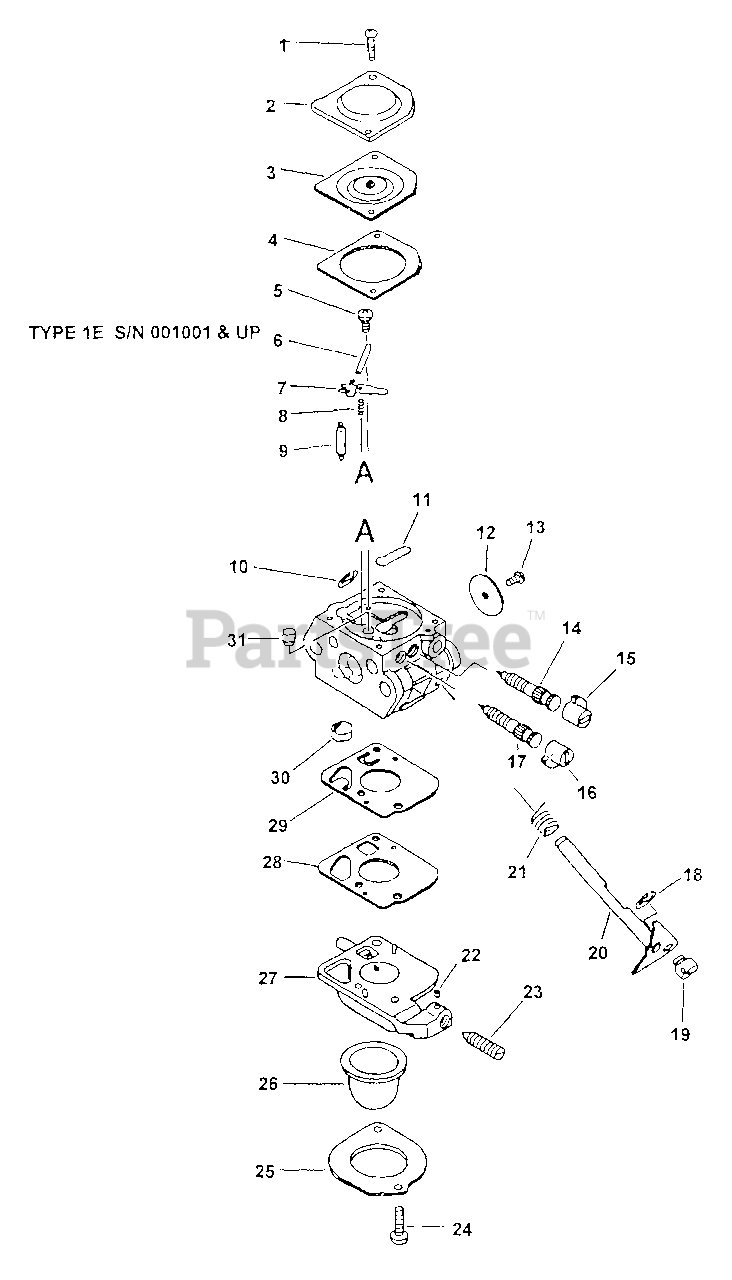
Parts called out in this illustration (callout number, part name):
2	COVER, METERING
3	DIAPHRAGM, METERING
4	GASKET, METERING
5	SCREW, METERING LEVER PIN
6	PIN, METERING LEVER
7	LEVER, METERING
8	SPRING, METERING LEVER
9	VALVE, NEEDLE
10	RING, RETAINING
11	PLUG, WELCH
12	VALVE, THROTTLE
14	NEEDLE - LOW SPEED
15	CAP, LIMITER
16	CAP, LIMITER
17	NEEDLE - HIGH SPEED
18	RING, RETAINING
20	SHAFT, THROTTLE
21	SPRING, RETURN
22	PIECE, FRICTION
23	SCREW, IDLE ADJUST
24	SCREW, RETAINER
25	RETAINER, PURGE BULB
26	BULB, PURGE
27	BASE, PURGE
28	GASKET, PURGE
29	DIAPHRAGM, PURGE
30	STRAINER
31	NOZZLE, CHECK VALVE
